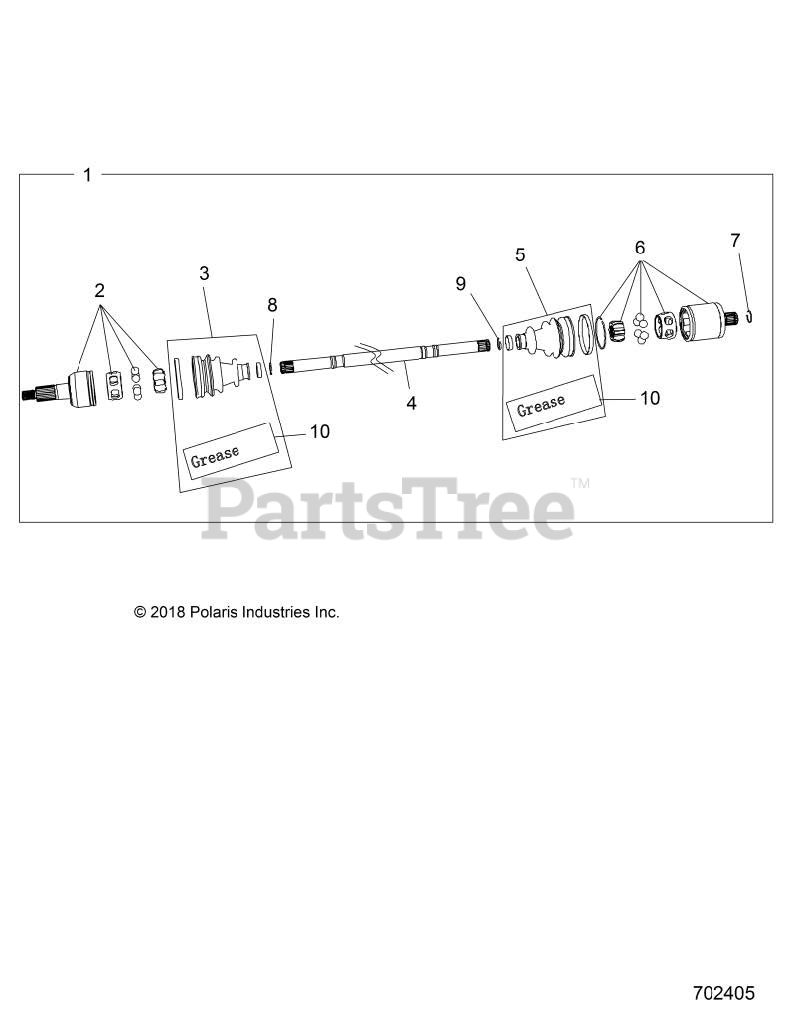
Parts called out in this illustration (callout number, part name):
1	ASM-HALFSHAFT,REAR
2	JOINT, OUTER
3	KIT-BOOT(PR-8071)
5	K - BOOT, INNER
6	JOINT, INNER
9	CIRCLIP(PR-3041)
10	GREASE(K575/VW738)
